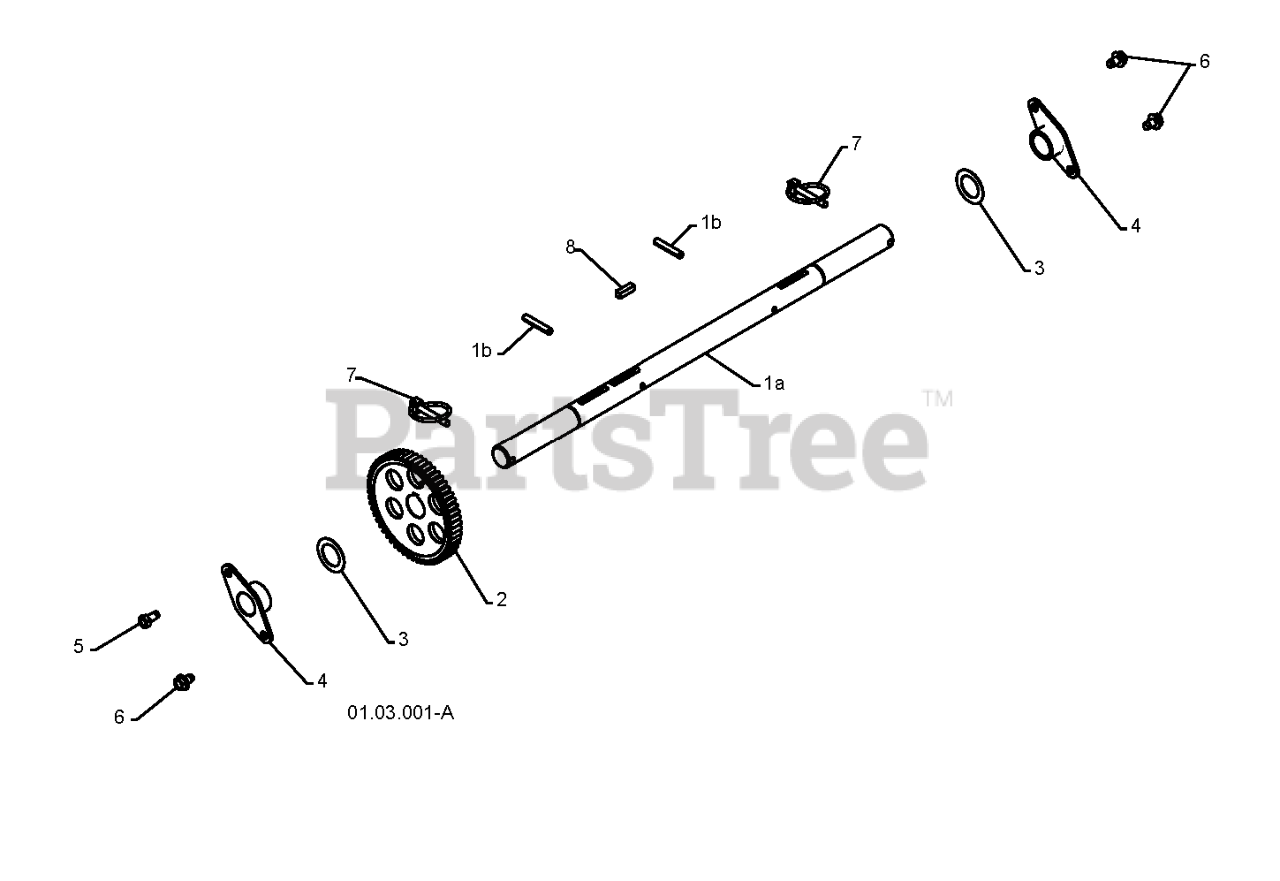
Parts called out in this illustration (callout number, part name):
1	AXLE.ASM.SHAFT.W/ROLLPIN.PS
2	GEAR, AXLE (58T)
3	WASHER TRUST 1"
4	BEARING, AXLE
6	Screw 5/16-18 x 1/2 Hex, Self Tapping 5/16-18 x 1/2
7	PIN KLIK, 1/4
8	KEY, SQUARE 1/4 X .875
